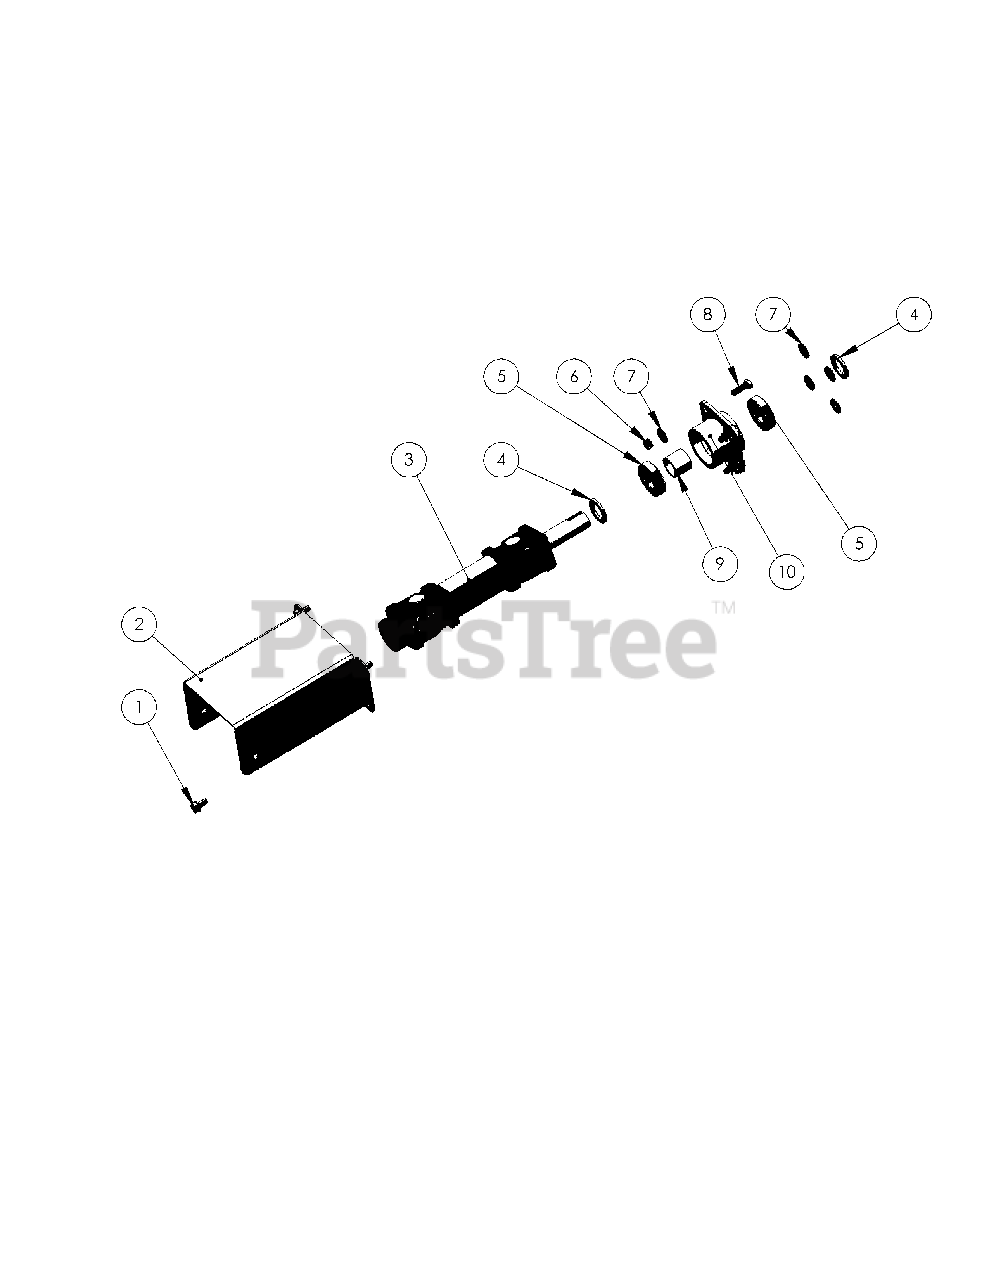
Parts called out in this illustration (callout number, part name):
1	5/16 Self Tapping Screw
4	Washer Spacer
6	5/16-18 Hex Nut
7	5/16 Washer
8	5/16 - 18 X 1" Bolt
9	Bearing Spacer
10	Bearing Housing
